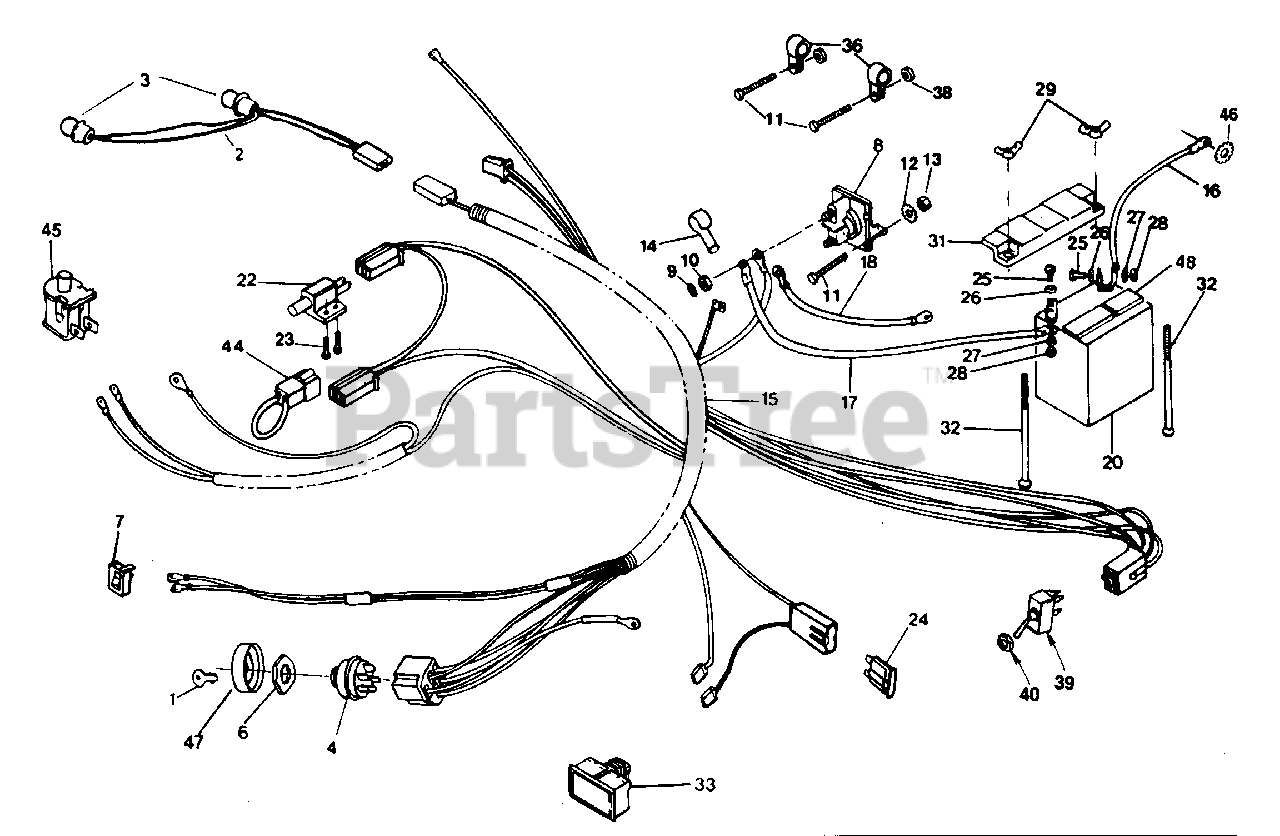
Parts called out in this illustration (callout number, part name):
1	Set Key (AYP part number)
2	Light Socket Harness (AYP part number)
3	Light Bulb (AYP part number)
4	Ignition Switch (AYP part number)
5	Cable Tie (AYP part number)
6	Hex Nut (AYP part number)
7	Light Switch (AYP part number)
8	Solenoid (AYP part number)
9	Lock Washer (AYP part number)
10	Jam Nut 1/4-20 (AYP part number)
11	Hex Bolt 1/4-20 x 1/2 Gr. 5 (AYP part number)
12	Lock Washer, Ext. Tooth (AYP part number)
13	Keps Nut (AYP part number)
14	Terminal Cover (AYP part number)
15	Ignition Harness
16	Battery Cable (AYP part number)
17	Battery Cable (AYP part number)
18	Ground Cable (AYP part number)
20	Battery Pack (AYP part number)
22	Interlock Switch (AYP part number)
23	Tap Washer Hex Screw (AYP part number)
24	30 Amp Fuse (AYP part number)
25	Hex Bolt 1/4-20 x 3/4 (AYP part number)
26	Washer 9/32 x 5/8 x 16 Ga. (AYP part number)
27	Lock Washer 1/4 (AYP part number)
28	Hex Nut 1/4-20 (AYP part number)
29	Wing Nut (AYP part number)
31	Terminal Guard (AYP part number)
32	Sq. Neck, Round Hd. Bolt (AYP part number)
33	Ammeter (AYP part number)
36	Insulation Clip (AYP part number)
38	Crownlock Nut (AYP part number)
39	P.T.O. Switch (AYP part number)
44	Wire Loop (AYP part number)
45	Plunger Switch (AYP part number)
46	Ext. Tooth Lock Washer (AYP part number)
47	Ignition Bezel (AYP part number)
48	Battery Caps (AYP part number)
